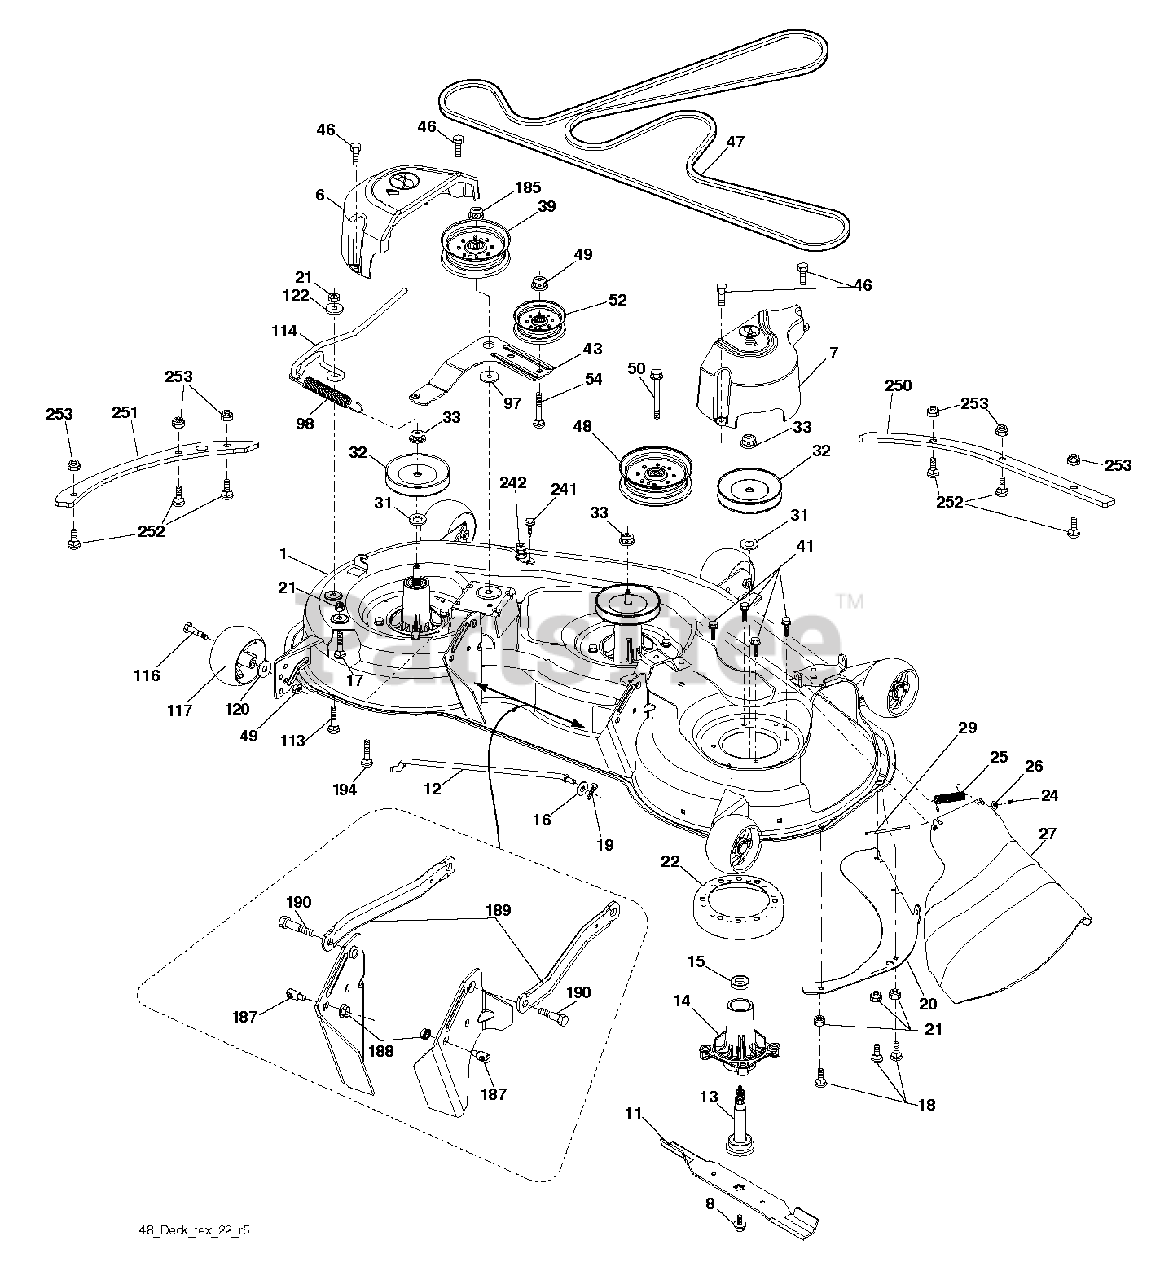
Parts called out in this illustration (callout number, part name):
6	COVER.MANDREL.LH.48"
7	Mandrel Cover, RH 48"
8	BOLT.WASHER.ASM.7/16-2
11	48" HI-LIFT BLADE
12	ROD.ANTI.SWAY.48/54"K4
13	SHAFT ASM MANDREL
14	HOUSING MANDREL
16	WASHER
17	BOLT
18	BOLT
19	PIN.COTTER.5/16.BOW TI
20	BAFFLE, VORTEX MWR
21	LOCKNUT
22	STRIPPER, MWR ROUND
24	CAP-SLEEVE LT
25	SPRING, TORSION
26	NUT PUSH M
27	DEFLECTOR SUBS TO 532 180655
29	ROD.HINGE
31	WASHER.SPACER.MANDREL
32	PULLEY MANDREL
33	NUT.FLANGE.LOCK.TOP
39	PULLEY.IDLER.4.50/HUB SPECIAL
41	Hex Washer Head Bolt, .313-18 X 1.19
43	ARM.IDLER
46	SCREW.1/4-20X5/8
47	BELT.DRIVE.DECK
48	PULLEY.IDLER.2006
49	NUT LOCK FLG 3/8-16 UNC
50	SCREW TT 3/8-16X2-1/4 UNC
52	PULLEY.IDLER.48"PRIMARY
54	BOLT.3/8-16X1.50
98	SPRING, DECK DRIVE
114	ROD.TENSION.RELIEF.TEX
116	BOLT.SHOULDER.3/8-16X3-5/8
117	WHEEL. GUAGE RALLY
122	BUSHING.RELIEF.TENSION
185	NUT.LOCK.FLANGE.7/16
187	STUD.FASTNER.W/ANTI-ROTATE
188	NUT LOCK HEX FLANGE 5/16-18
189	ARM.SUSPENSION.MOWER
190	BOLT.SHOULDER
194	BOLT.HEX.WASHER.HEAD.7/16-24X
242	PORT.WASHOUT
250	Front Reinforcement Plate, 48" Bolt-on
251	Side Reinforcement Plate, 48" Bolt-on
252	RHSNB, 1/4-20 X 1, GR5
253	NUT T
